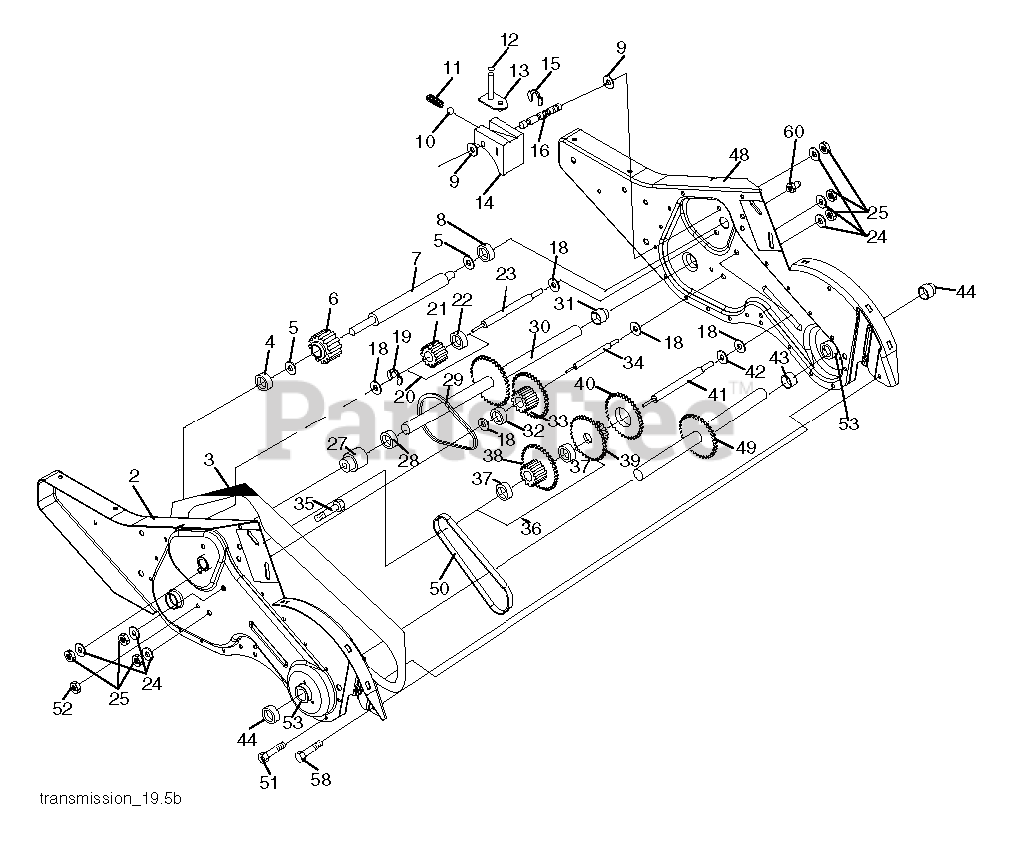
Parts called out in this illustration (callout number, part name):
1	TRANSMISSION ASM.
2	GEARCASE.ASM.CRT.LH.W/BEARING
3	GASKET
4	NEEDLE BRNG LT
5	THRUST WASHER
6	GEAR.PINION.INPUT
7	SHAFT.INPUT."D".TILLER
8	BEARING TI
9	WASHER, SEAL (2 2)
10	STEEL BALL KIT
11	SPRING-SHIFT CRT
13	BRACKET ASM.SHIFT.CRT
14	SHIFT FORK TI
16	SHAFT.SHIFTER.TILLER
20	GEAR ASSY CRT
21	GEAR-REV IDLR CRT
22	NEEDLE BEARING TI
24	LOCKWASHER
25	NUT.ASF.HEX.7/16
27	BEARING, SHAFT LH CRT
30	GROUND SHAFT ASS'Y
31	BEARING, SHAFT RH CRT
33	SPRCKT 8 GEAR CRT
34	SHAFT.SECONDARY.REDUCTION.CRT
35	SCRW WHIZ LOK CRT
36	SPROCKET.ASM.W/BEARING.TILLER
37	BEARING
38	SPROCKET, TINE
41	SHAFT.REDUCTION.TILLER
42	BRNG RACE T
44	SEAL ASM, OIL
48	GEARCASE.ASM.CRT.RH.W/BEARING
49	TINE SHAFT
50	CHAIN.TILLER
51	SCREW
53	KIT.BEARING.TILLER.
58	BOLT SHOULDER 1/4-20 UNC X.875
60	FITTING.GREASE.TAPERED
